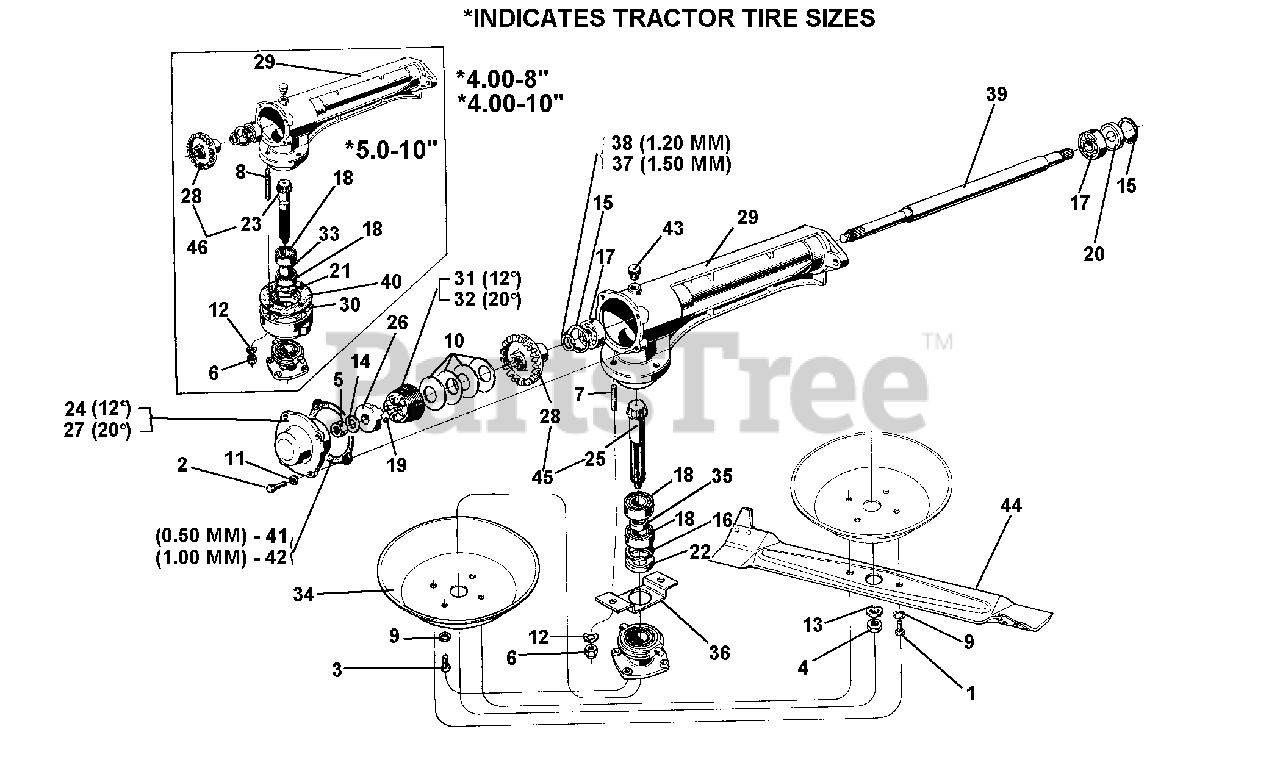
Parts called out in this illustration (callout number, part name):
1	SCREW M8 X 16
2	SCREW M6 X 20
3	SCREW M8 X 12
4	NUT, LOW M12
5	NUT M10 X 1.5
6	NUT, SELF LOCKING M10 LOW
7	STUD M10 X 37 X 19 X 15 8G
8	STUD M10 X 68 X 34 X 15
9	SUPER WASHER 8 DIN 6796
10	SPRING 56 X 28 X .5 X 1.5
11	WASHER, LOCK 6.4
12	WASHER, LOCK 10.5
13	WASHER, LOCK 13
14	WASHER, LOCK 15
15	CIRCLIP, INTERN. D 47
16	CIRCLIP, INTERN. D 52
17	BEARING 20 X 47 X 14 6204
18	BEARING 25 X 52 X 15 6205
19	BALL 5/16 RIV RB 7.938
20	OIL SEAL 20 X 47 X 7
21	OIL SEAL 25 X 40 X 7
22	OIL SEAL 25 X 52 X 7
23	BEVEL PINION
26	BRAKE COUPLING
28	CONICAL GEAR
29	LAWN MOWER CASING 715
30	SPACER FLANGE
33	LONG SPACER
34	PROTECTION DISC
39	PROPELLER SHAFT
43	BREATHER CAP 1/4 GAS
44	LAWN MOWER BLADE
